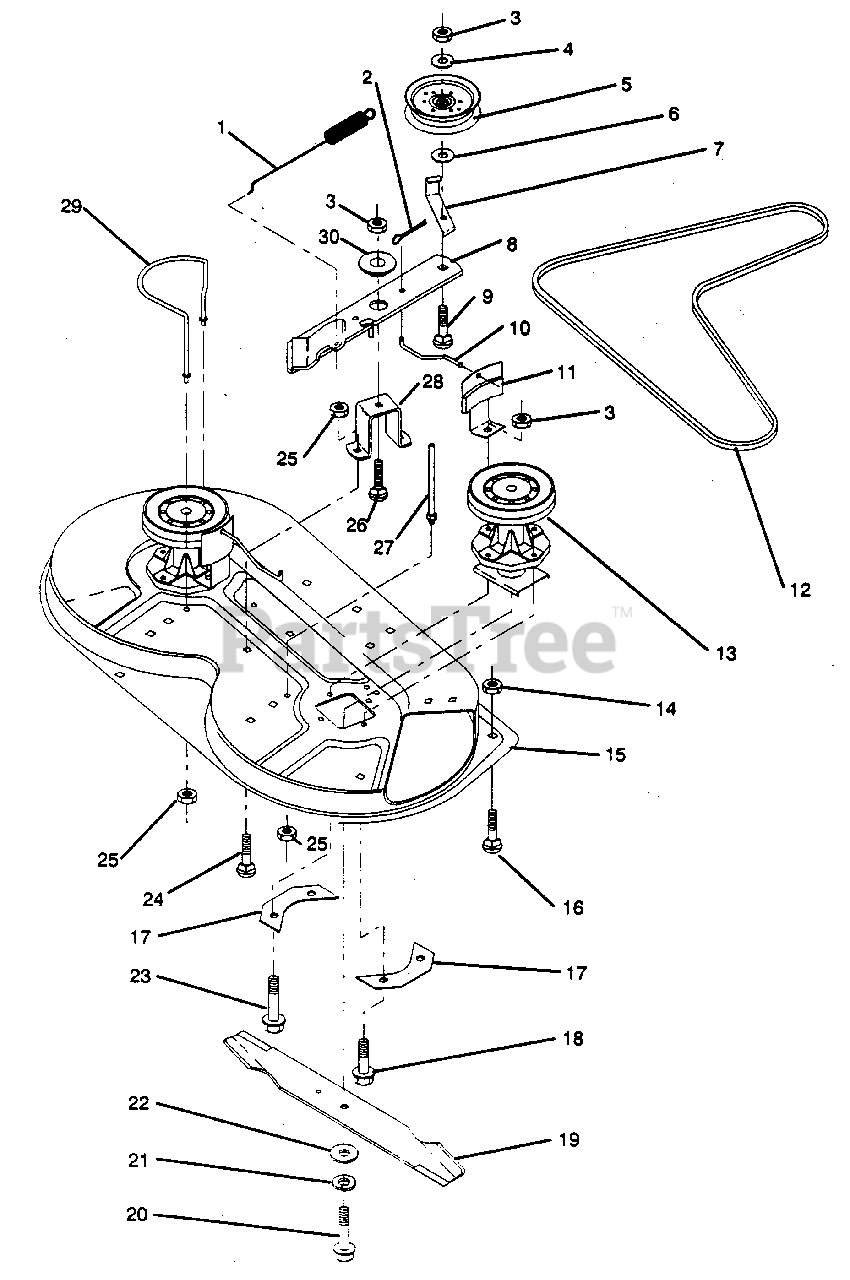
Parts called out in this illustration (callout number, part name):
1	Spring, Mower Clutch (AYP part number)
2	Pin, Cotter 3/32 x 3/4 (AYP part number)
3	Nut, Crownlock 3/8-16 UNC
4	Washer 13/32 x 7/8 x 12 Ga. (AYP part number)
5	Idler, Flat (AYP part number)
6	Washer 13/32 x 1-3/8 x 3 Ga. (AYP part number)
7	Guide, Belt (AYP part number)
8	Assembly, Mower Idler Arm (AYP part number)
9	Bolt, Carriage 3/8-16 x 2 1/4 (AYP part number)
10	Rod, Brake (AYP part number)
11	Assembly, Brake (AYP part number)
12	V-Belt (AYP part number)
13	Assembly, Mandrel
14	Nut, Crownlock 1/4-20 (AYP part number)
15	Housing, Mower 36" (AYP part number)
16	Bolt, Carriage 1/4-20 x 1/2 (AYP part number)
17	Support, Plate Jackshaft (AYP part number)
18	Screw Hex Thdrol. 3/8-16 x 7/8 (AYP part number)
19	Blade, Low Lift (AYP part number)
20	Bolt, Fin. Hex 3/8-24 UNF x 1-1/2 Gr. 5 (AYP part number)
21	Washer, Lock Hvy.3/8 (AYP part number)
22	Washer 13/32 x 1-1/4 x 12 Ga. (AYP part number)
23	Screw Hex Thdrol. 3/8-16 x 1-1/4 (AYP part number)
24	Bolt, Carriage 5/16-18 UNC x 5/8 (AYP part number)
25	Nut, Crownlock 5/16-18
26	Bolt, Carriage 3/8-16 UNC x 1 Gr. 5 (AYP part number)
27	Guide, R.H. Rear Belt (AYP part number)
28	Support, Idler Arm (AYP part number)
29	Guide, L.H. Belt (AYP part number)
30	Spacer, Retainer (AYP part number)
